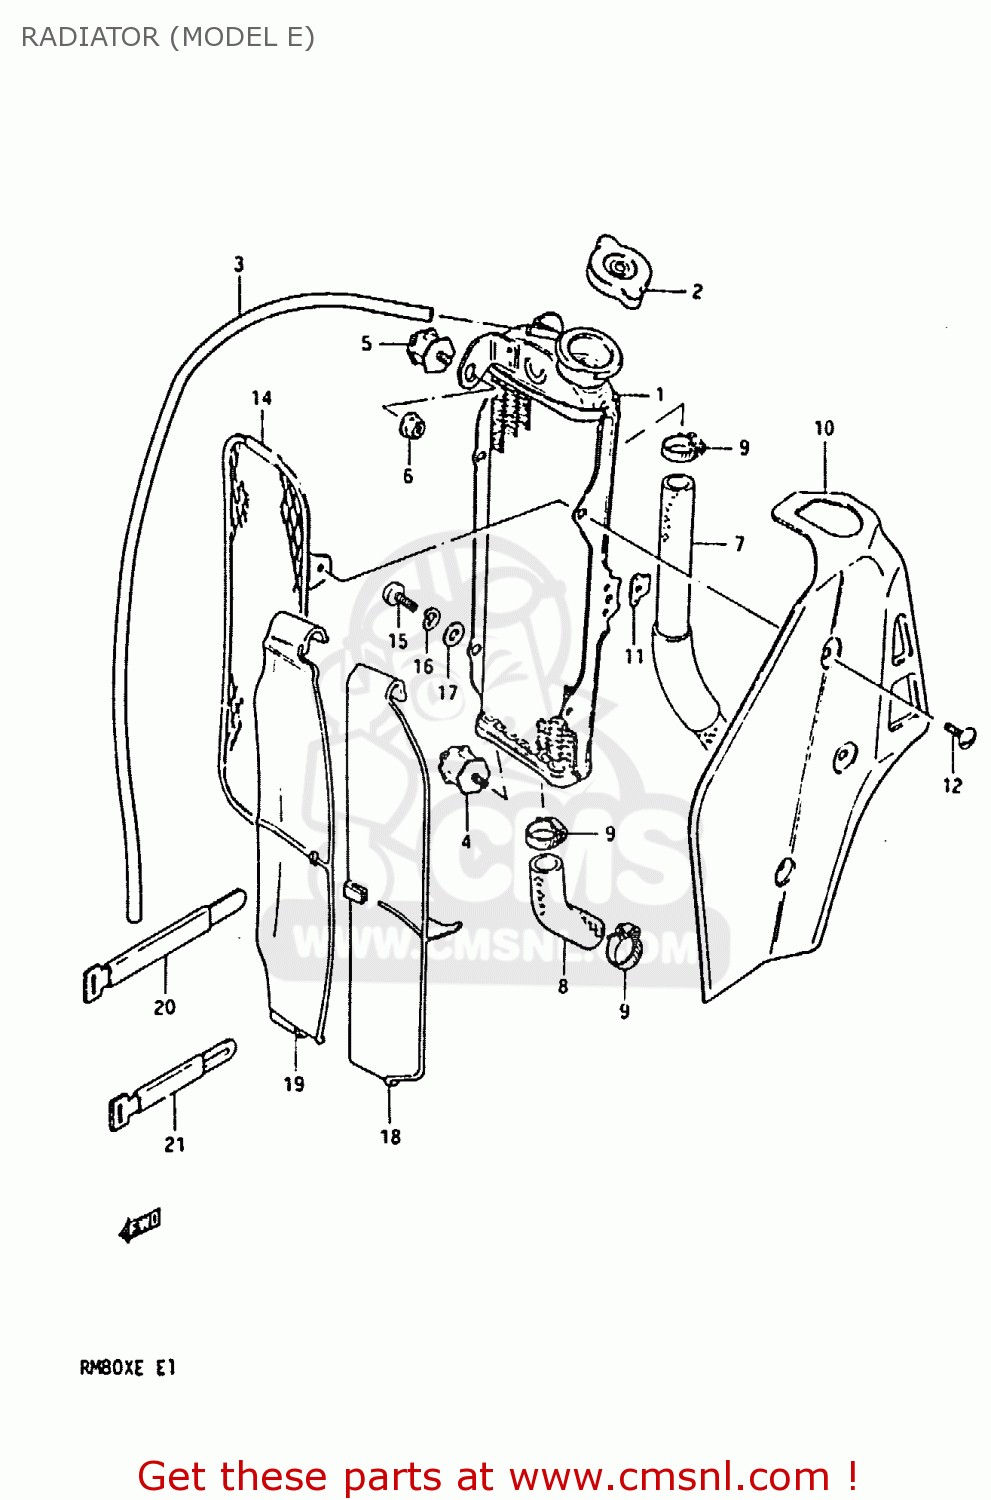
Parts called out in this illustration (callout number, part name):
1	RADIATOR ASSEMBLY,WATER
2	CAP,RADIATOR 1.1
3	HOSE
4	CUSHION,RADIATOR
5	CUSHION
6	NUT
7	HOSE,RADIATOR INLET
8	HOSE,RADIATOR OUTLET
9	CLAMP
10	COVER,RADIATOR
11	PLATE,RADIATOR COVER FITING
12	SCREW(6X14)
13	WASHER(5.2X16X1)
14	BUMPER,RADIATOR
15	SCREW
16	LOCK WASHER
17	WASHER
18	LOUVER,RADIATOR
19	LOUVER,RADIATOR
20	CLAMP
21	CLAMP
